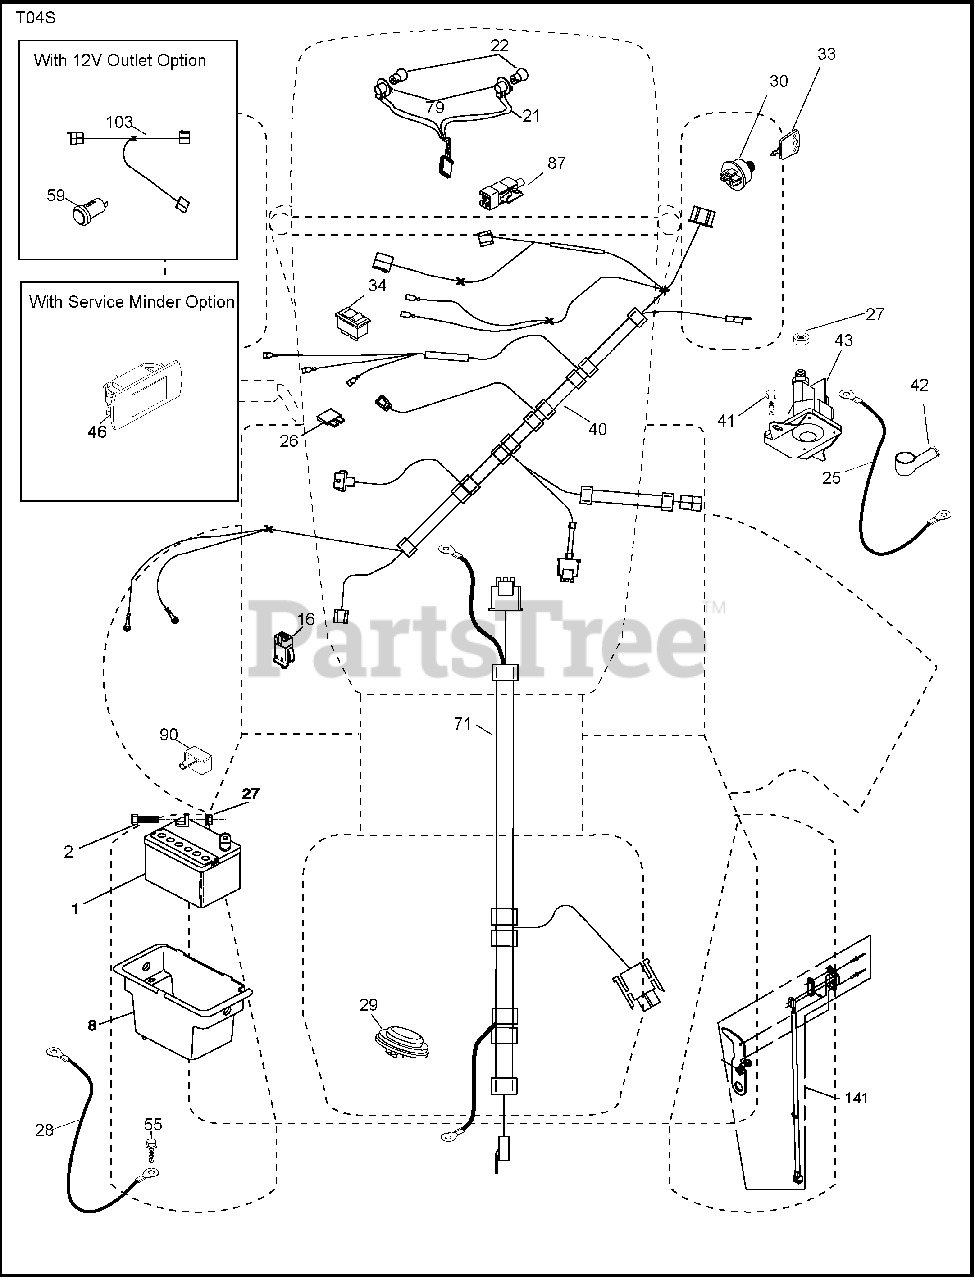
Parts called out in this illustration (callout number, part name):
1	Battery
2	Bolt Hex Head 1/4-20 x 3/4
8	Box Battery
16	Switch Interlock Push-In
21	Harness Socket Light w/4152J
22	Bulb Light
25	Cable Starter
26	Fuse
27	Nut Keps Hex 1/4-20 unc
28	Cable, Ground
29	Switch, Seat
30	Switch, Ignition
33	Key/Chain
34	Switch Light/Reset
40	Harness Ignition Dash
41	Screw Thd Cut 1/4-20 x 1/2
42	Cover, Terminal
43	Solenoid
46	Gauge SRVCMNDR HRMTR
55	Screw Thdrol 5/16-18 x 3/4 TYTT
71	Harness Ignition
79	Socket Asm Bulb Twistlock
87	Switch Interlock Clutch Cable
90	Cover Terminal Battery
141	Kit T2 ROS
